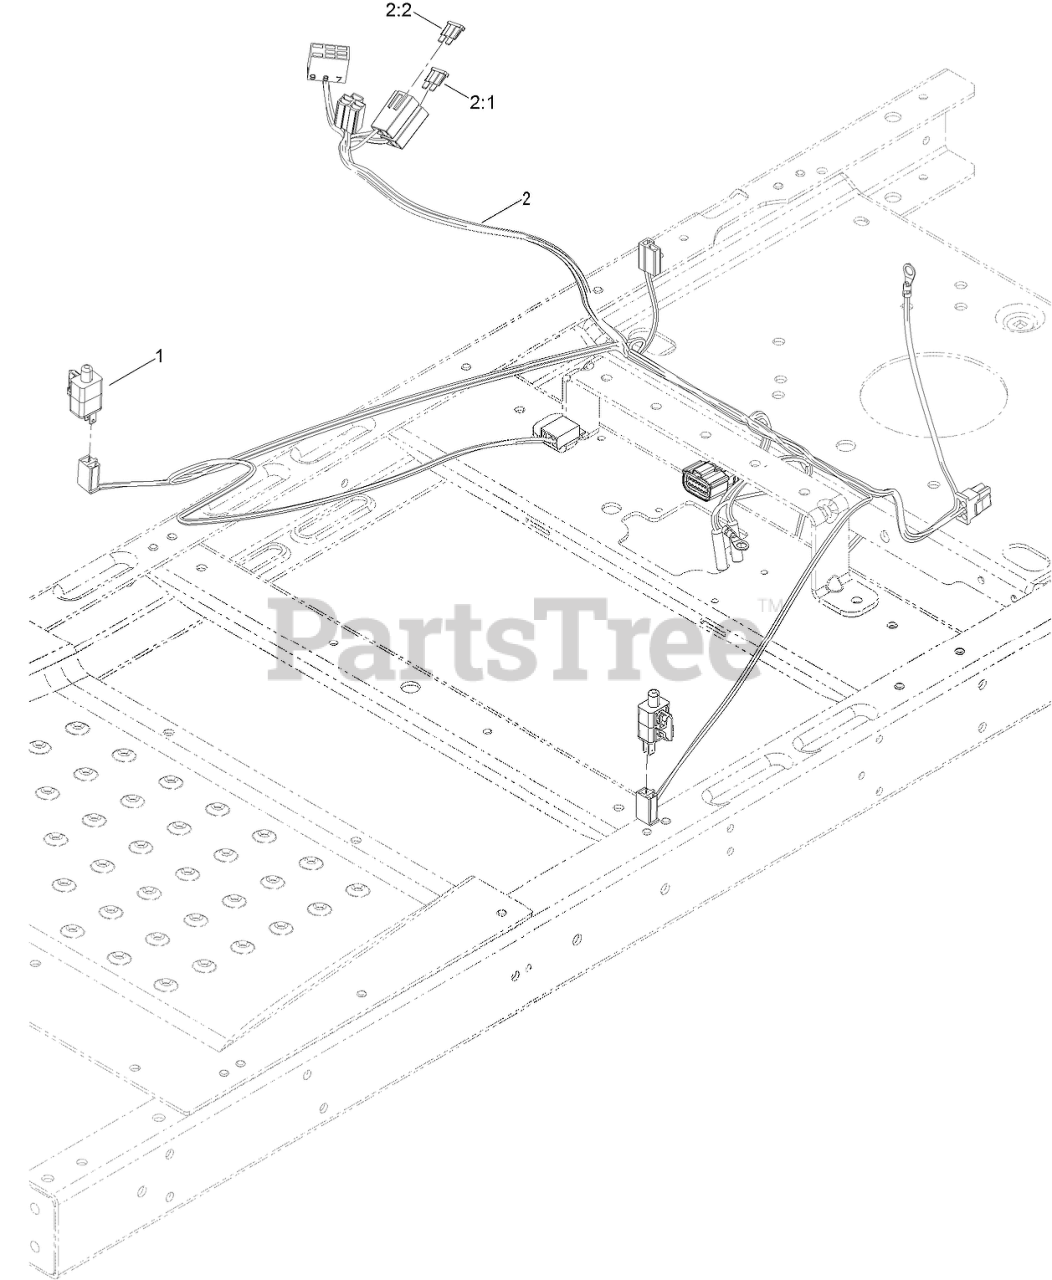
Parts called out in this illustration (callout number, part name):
1	SWITCH
2	HARNESS-WIRE
2:1	FUSE-BLADE, 30 AMP
2:2	FUSE-BLADE, 25 AMP
